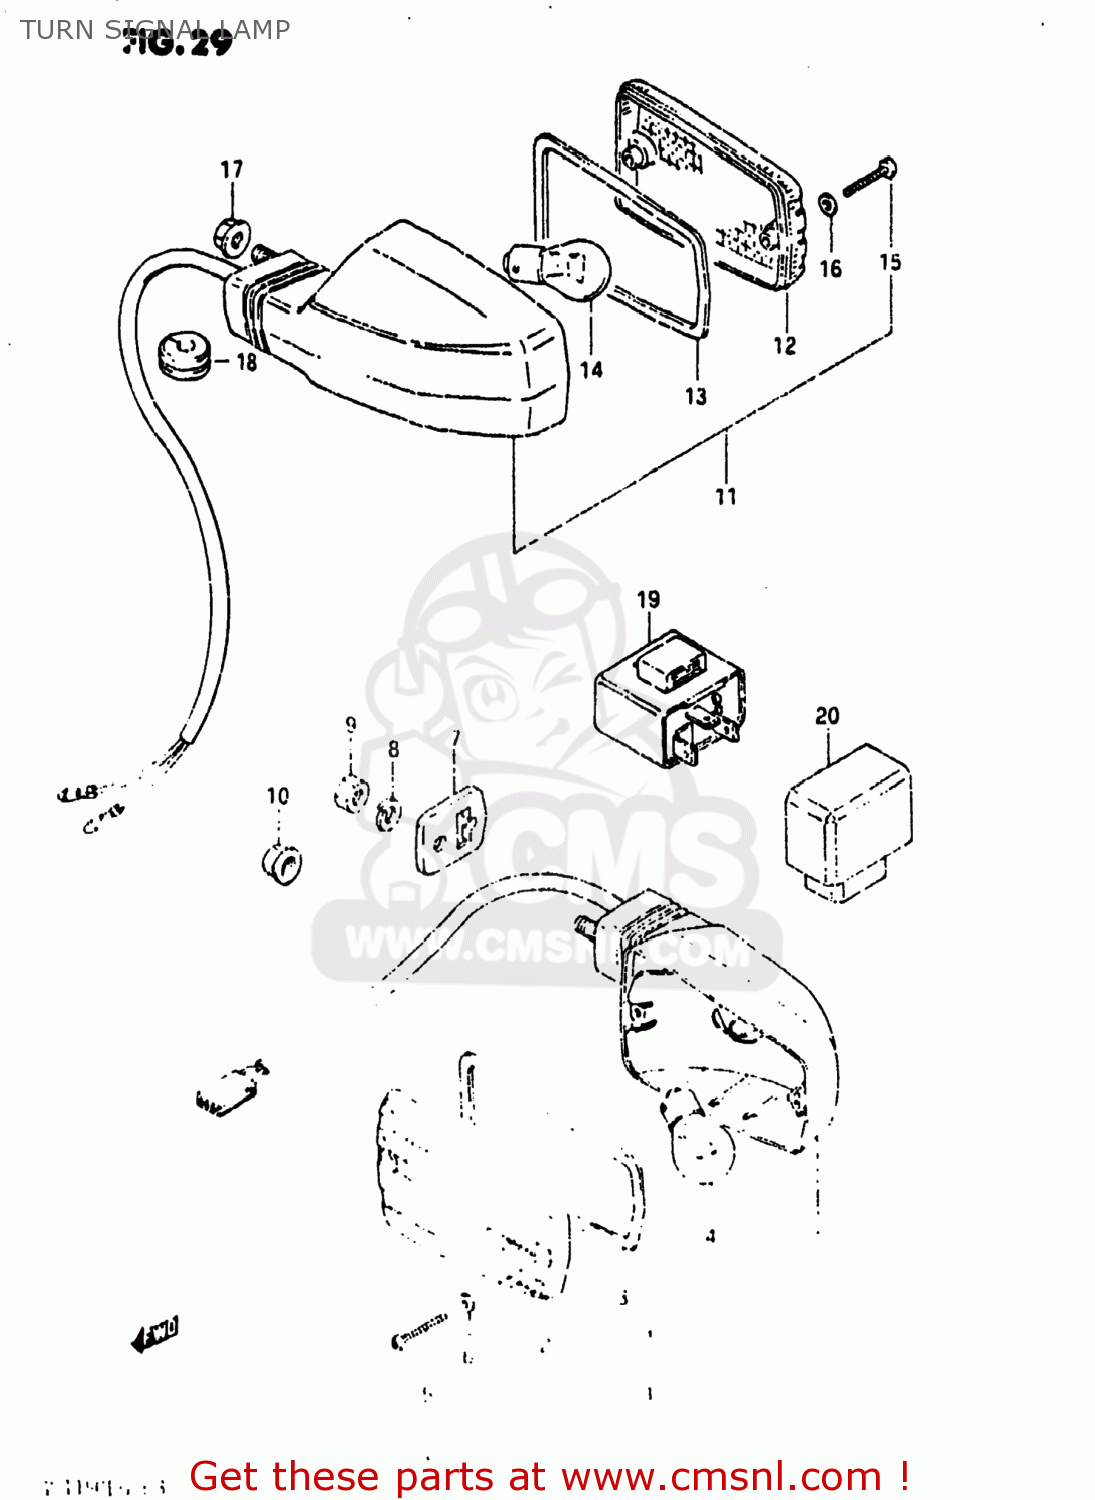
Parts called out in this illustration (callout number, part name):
1	LAMP ASSEMBLY,FRONT TURN SIGNAL
2	LENS,TURN SIGNAL LAMP
3	GASKET (NAS)
4	BULB(12V23W)
5	SCREW
6	GASKET (NAS)
7	SPACER,FRONT TURN SIGNAL
8	LOCK WASHER
9	NUT
10	NUT
11	LAMP ASSEMBLY,FRONT TURN SIGNAL
12	LENS
13	GASKET (NAS)
14	BULB(12V23W,STANLEY,A4577A)
15	SCREW
16	GASKET (NAS)
17	NUT
18	GROMMET
19	RELAY ASSY,TURNSIGNAL
20	UNIT,TURN SIGNAL CONTROL
